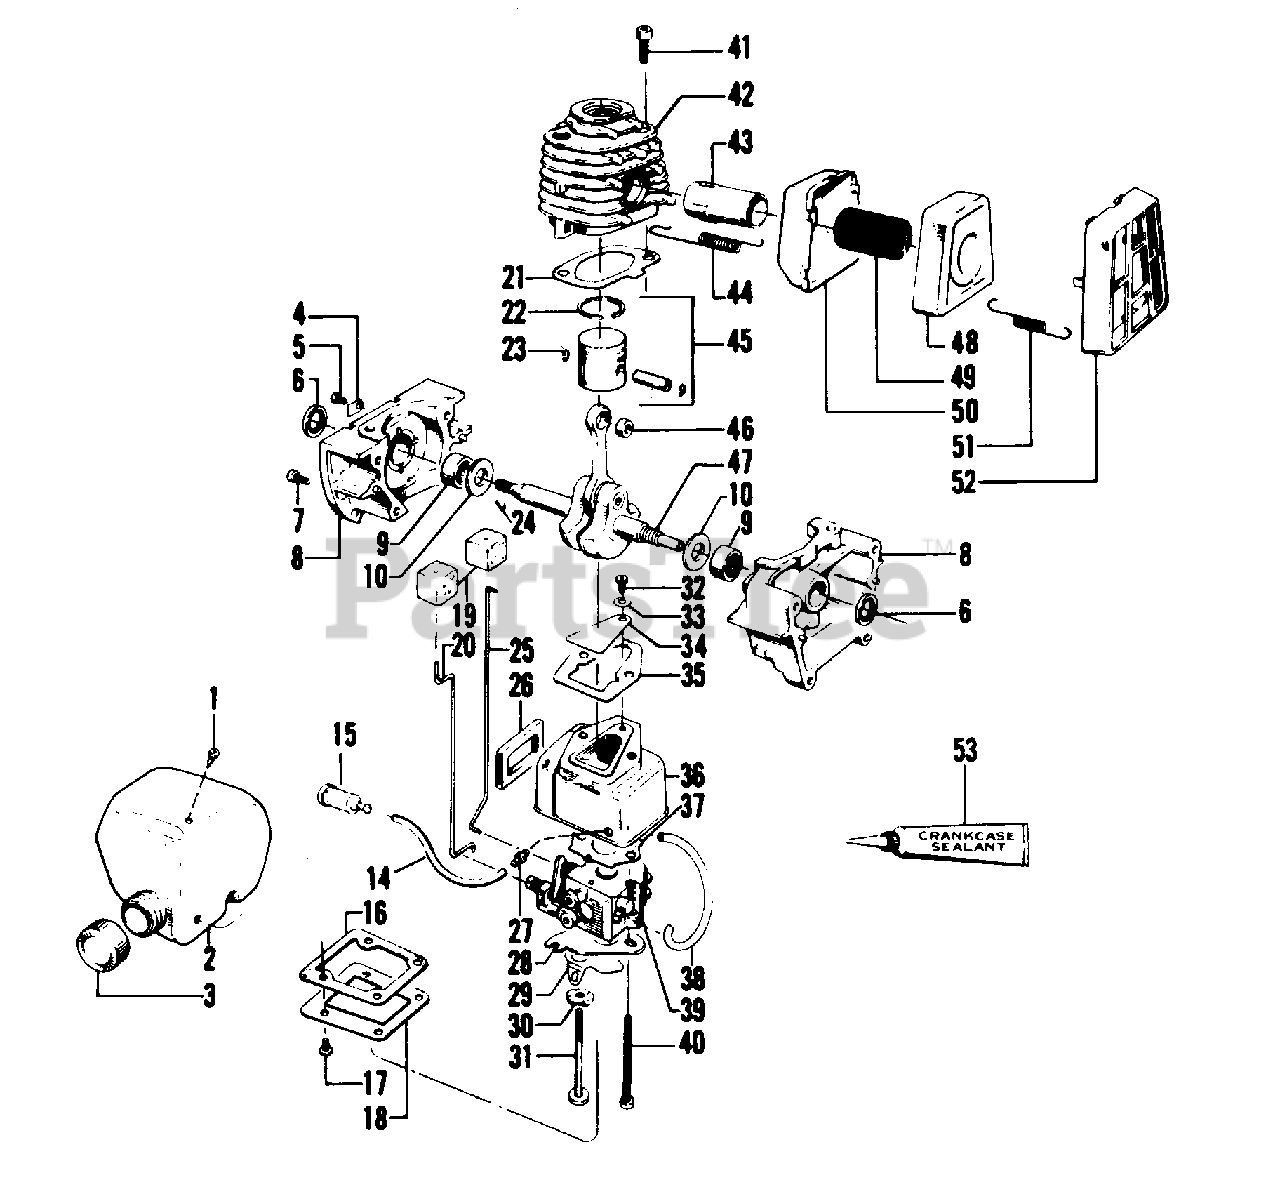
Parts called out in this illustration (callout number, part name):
1	Duck Bill Valve
2	Fuel Tank Ass'y (Incl. #1, 3, 14 & 15)
3	Fuel Cap (Incl. O-Ring)
4	Clamp - Choke Wire
5	Screw - #8 - 32 x 5/16" - Choke Wire Clamp
6	Seal - Crankcase
7	Screw - #10 - 24 x 5/8" - Crankcase
8	Crankcase Assembly (Inc.6, 9 & Qty 4 of 7)
9	Bearing - Crankshaft
10	Washer - Crankshaft Thrust
14	Fuel Line
15	Fuel Pick-Up Assembly
16	Gasket - Carburetor Case Cover
17	Screw - #8 - 18 x 9/16" - Carburetor Case Cover
19	Boot - Throttle - Choke Wire
21	Gasket - Cylinder
22	Piston Ring
23	Retainer - Wrist Pin
24	Key - Flywheel
25	Throttle Wire
26	Seal - Carburetor Case
27	Fuel Line Fitting
29	Choke Shutter
30	Wave Washer
31	Screw - #10 - 24 x 2-1/8" - Fil. Hd. - Carburetor Shoulder
32	Screw - #6 - 19 x 5/16" - Pan Hd. Reed Valve
33	Washer - #6 - Reed Valve Screw
34	Reed Valve
35	Gasket - Carburetor Housing to Crankcase
36	Carburetor Housing
37	Carburetor Gasket
38	Fuel Line - Carburetor
39	Carburetor - See Service Ref. 3
40	Screw - #10 - 24 x 1-7/8" - Carburetor
41	Screw - #1/4 - 20 x 3/4" - Cylinder
42	Cylinder
43	Diffuser - Muffler
44	Spring - Muffler Attachment
45	Piston Assembly (Inc. 22, 23, & Pin)
46	Bearing - Wrist Pin
47	Crankshaft & Rod Assembly
48	Cover - Muffler
49	Screen - Spark Arresting
50	Body - Muffler
51	Spring - Muffler Guard
52	Guard - Muffler
53	Crankcase Sealant - 3 oz. Tube (Optional)
